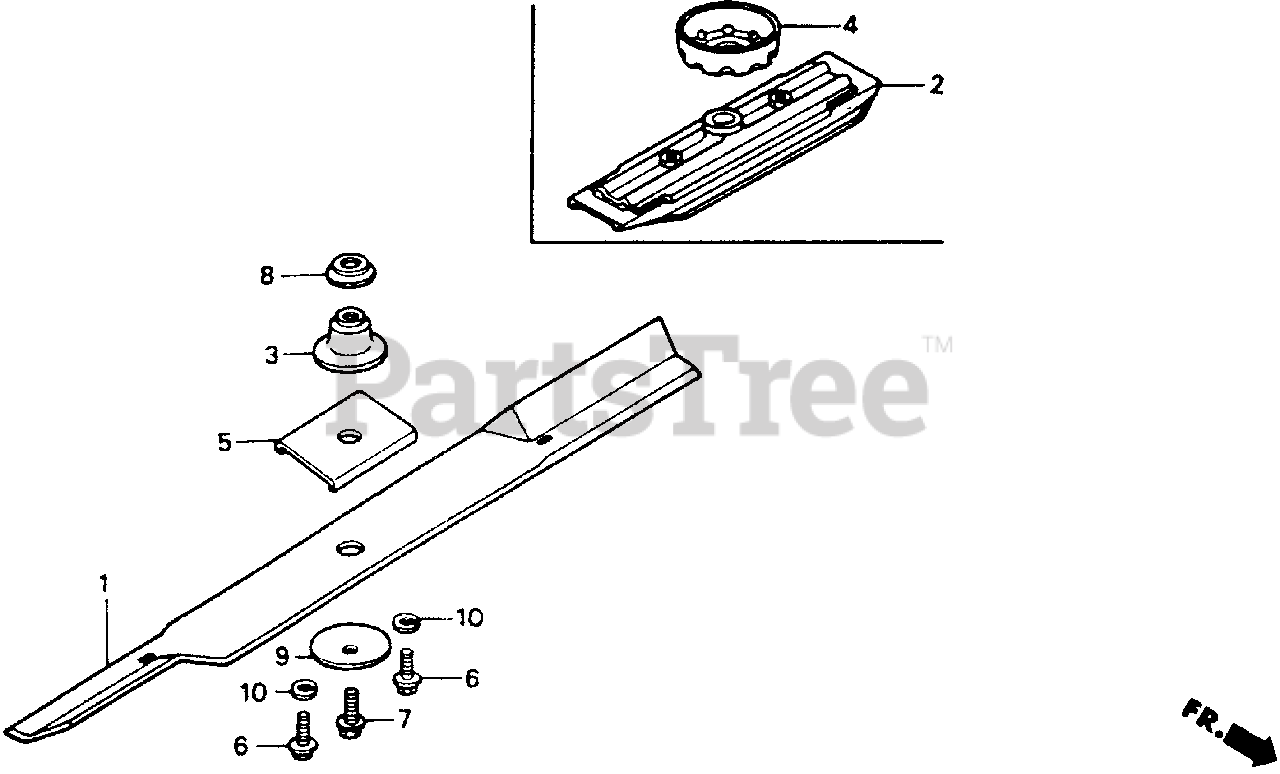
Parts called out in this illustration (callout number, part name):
1	BLADE, ROTARY
2	HOLDER, BLADE
4	COVER, BEARING
6	BOLT, FLANGE (12X25)
7	BOLT, SPECIAL (12X25)
10	WASHER, SPRING (12MM)
